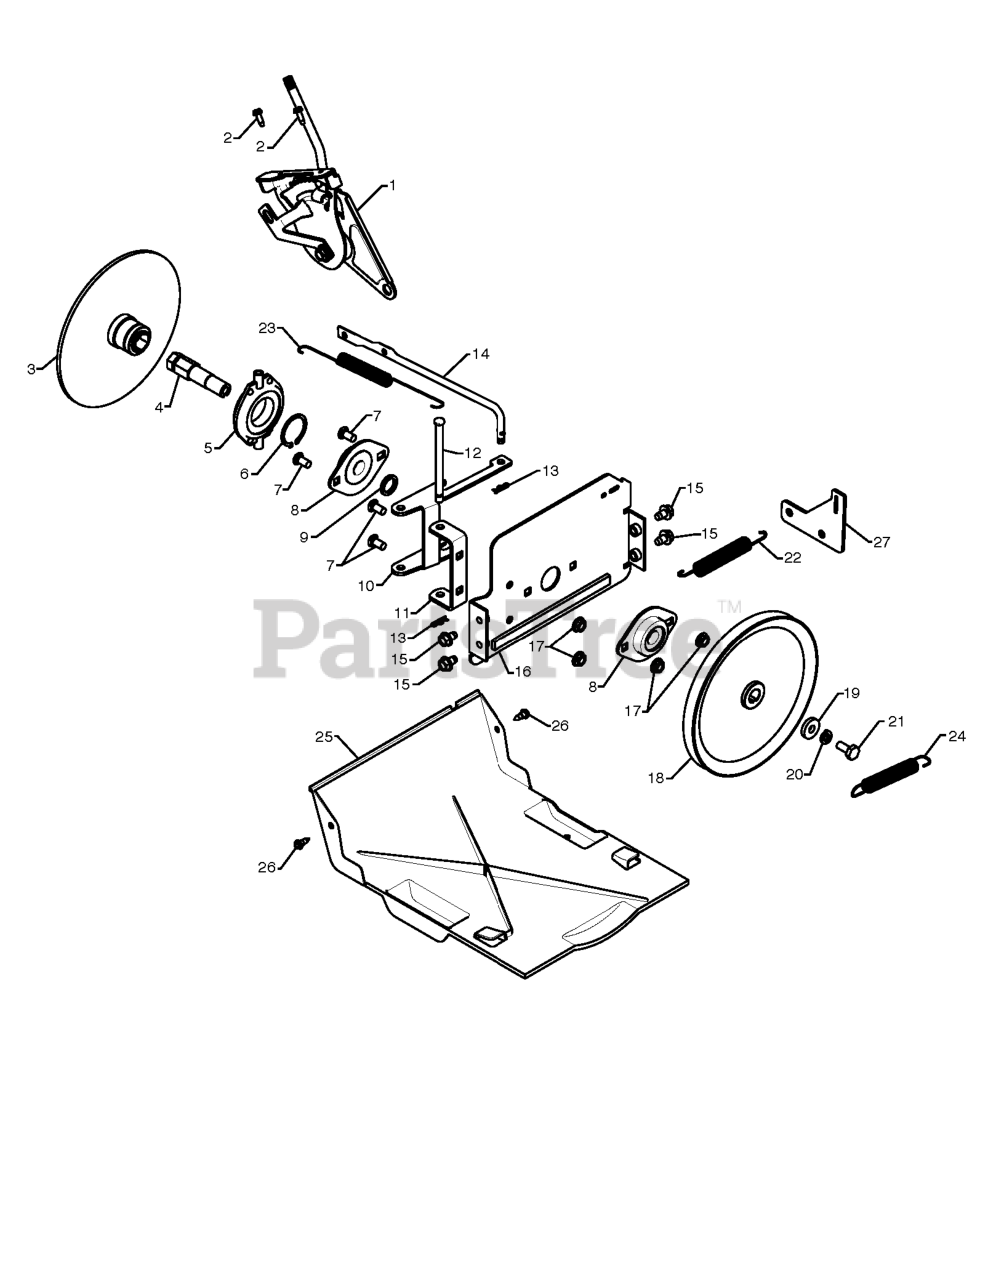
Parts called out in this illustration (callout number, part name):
1	HEAD ASSY SPEED
2	SCREW #10-24 X 5/8
3	DRIVE PLATE WELDMENT
4	SHAFT.HEX.SHORT
5	TRUNNION BEARING ASSY
6	RETAINING RING (2 2)(3 2)
7	BOLT
8	BEARING FLANGE
9	SPACER, BEARING
10	LEVER.SHIFTER.PLATE.BLACK
11	BRACKET, SHIFTER SUPPORT
12	PIN, PIVOT LEVER
13	RETAINER CLIP PM
14	ROD.CLUTCH.YELLOW.ZINC(VT)
15	Screw 5/16-18 x 1/2 Hex, Self Tapping 5/16-18 x 1/2
16	PLATE.DRIVE.MOUNTING.BLACK
17	NUT.FLANGE.5/16
18	PULLEY.TRACTION.7.75
19	WASHER, FLAT
20	WASHER.LOCK.HVY.HLCL.SPR.5/16
21	Screw, Hex Head 5/16-18 x 3/4
22	SPRING.TRACTION.IDLER
23	SPRING.RETURN
24	SPRING, BRAKE
25	PAN.BOTTOM.PLASTIC
26	SCREW, HEX HEAD, TAPPING
27	BRACKET.TRACTION.SPRING.
